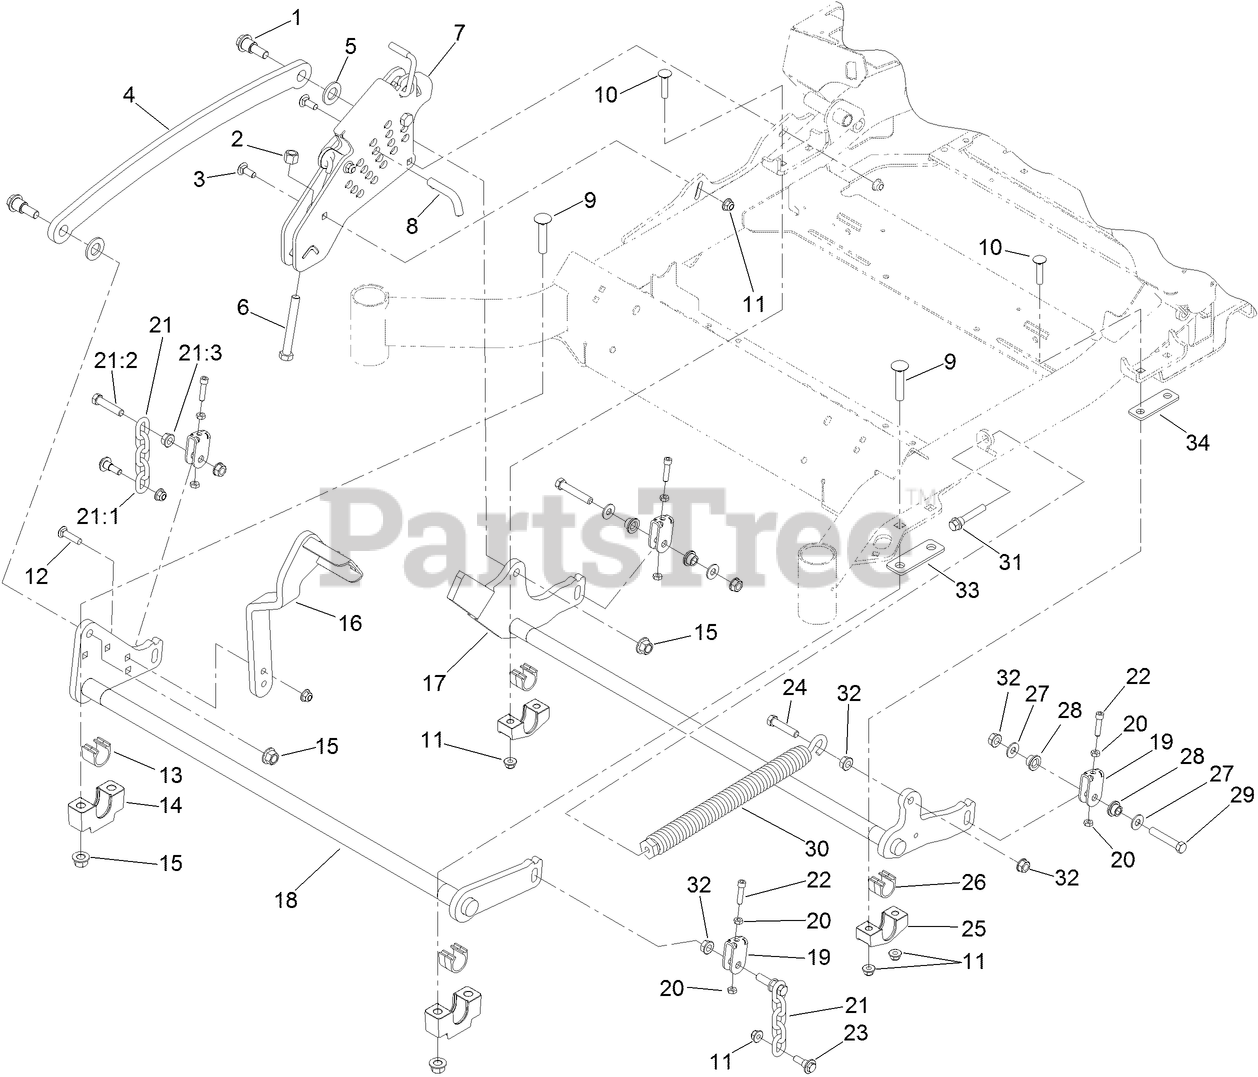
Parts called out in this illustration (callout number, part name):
1	SCREW-SHOULDER, HHF
2	NUT-LOCK, NI
3	BOLT-CARR
4	LINK-LIFT, DECK
5	WASHER-FLAT
6	BOLT-TAP
7	HOC ASM
8	PIN-HOC
9	BOLT-CARR
10	SCREW-CARR
11	NUT-HF, NI
12	SCREW-CARR
13	BEARING-CROSS SHAFT, FRONT
14	SUPPORT-CROSS SHAFT, BEARING
15	NUT-LOCK
16	LEVER-FOOT
17	LIFT-DECK, REAR
18	DECKLIFT-FRONT
19	YOKE-ADJUST, DECK
20	NUT-JAM
21	DECK LIFT CHAIN ASM
21:1	CHAIN-LIFT, DECK
21:2	SCREW-HH
21:3	NUT-HF
22	SCREW-HH
23	SCREW-SHOULDER, HHF
24	SCREW-HH
25	SUPPORT-CROSS SHAFT, BEARING REAR
26	BEARING-CROSS SHAFT, REAR
27	WASHER-FLAT
28	BUSHING-FLANGED
29	SCREW-HH
30	SPRING-EXTENSION
31	BOLT-SHOULDER
32	NUT-HF
33	SPACER-DECKLIFT, FRONT
34	SPACER-DECKLIFT, BACK
